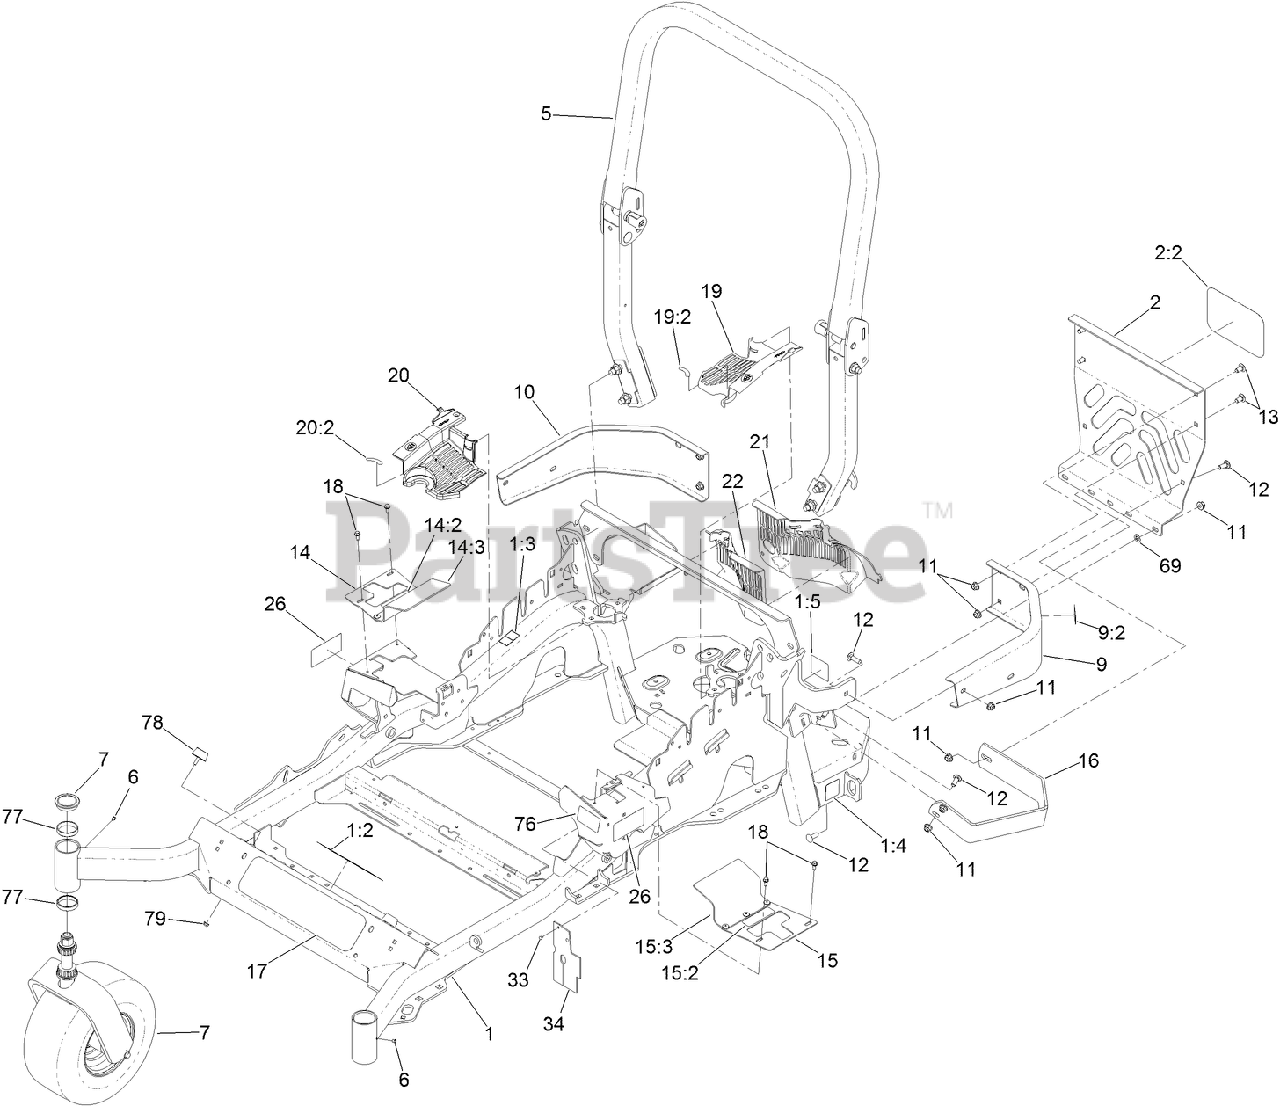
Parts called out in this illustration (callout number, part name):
1	MAINFRAME ASM
1:2	DECAL-WARNING
1:3	DECAL-DANGER
1:4	DECAL-HAZARD, PINCHED FINGER
1:5	DECAL-SPARK ARRESTER
2	REAR GUARD ASM
2:2	DECAL
5	ROPS ASM
7	Caster Wheel ASM
9	LH BUMPER ASM
9:2	DECAL-WARNING
10	BUMPER-RH
11	NUT-HF, NI
12	SCREW-CARR
13	SCREW-CARR
14	RH MOTION CONTROL COVER ASM
14:2	DECAL-CONTROL, MOTION
14:3	FLAP-RUBBER
15	LH MOTION CONTROL COVER ASM
15:2	DECAL-CONTROL, MOTION
15:3	FLAP-RUBBER
16	GUARD-MUFFLER
17	DECAL-Z MASTER, PROFESSIONAL
18	SCREW-HWH
19	LH HYDRO GUARD ASM
19:2	DECAL-OIL, HYDRO
20	RH HYDRO GUARD ASM
20:2	DECAL-OIL, HYDRO
21	GUARD-HYDRO REAR, LH TRIM
22	GUARD-HYDRO, REAR (RH)
33	RIVET-POP
34	DEFLECTOR-AIR FLOW
69	NUT-PUSH
76	DECAL-FUEL FILL, CE
77	CUP-BEARING
78	BUMPER
79	NUT-HF
